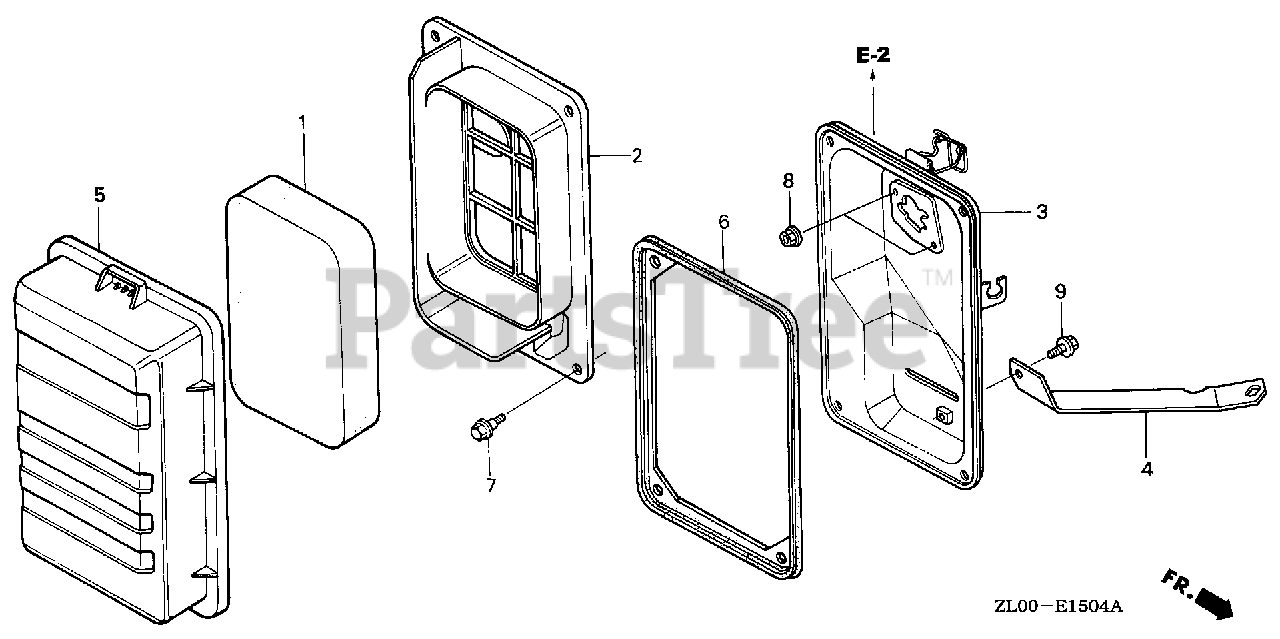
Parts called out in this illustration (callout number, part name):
1	ELEMENT, AIR CLEANER
2	SEPARATOR, AIR CLEANER
3	HOUSING, AIR CLEANER
4	STAY, AIR CLEANER
5	COVER, AIR CLEANER
6	SEAL, AIR CLEANER
7	BOLT, TURN SIGNAL SETTING
8	NUT, FLANGE (6MM)
9	BOLT, FLANGE (6X10)
